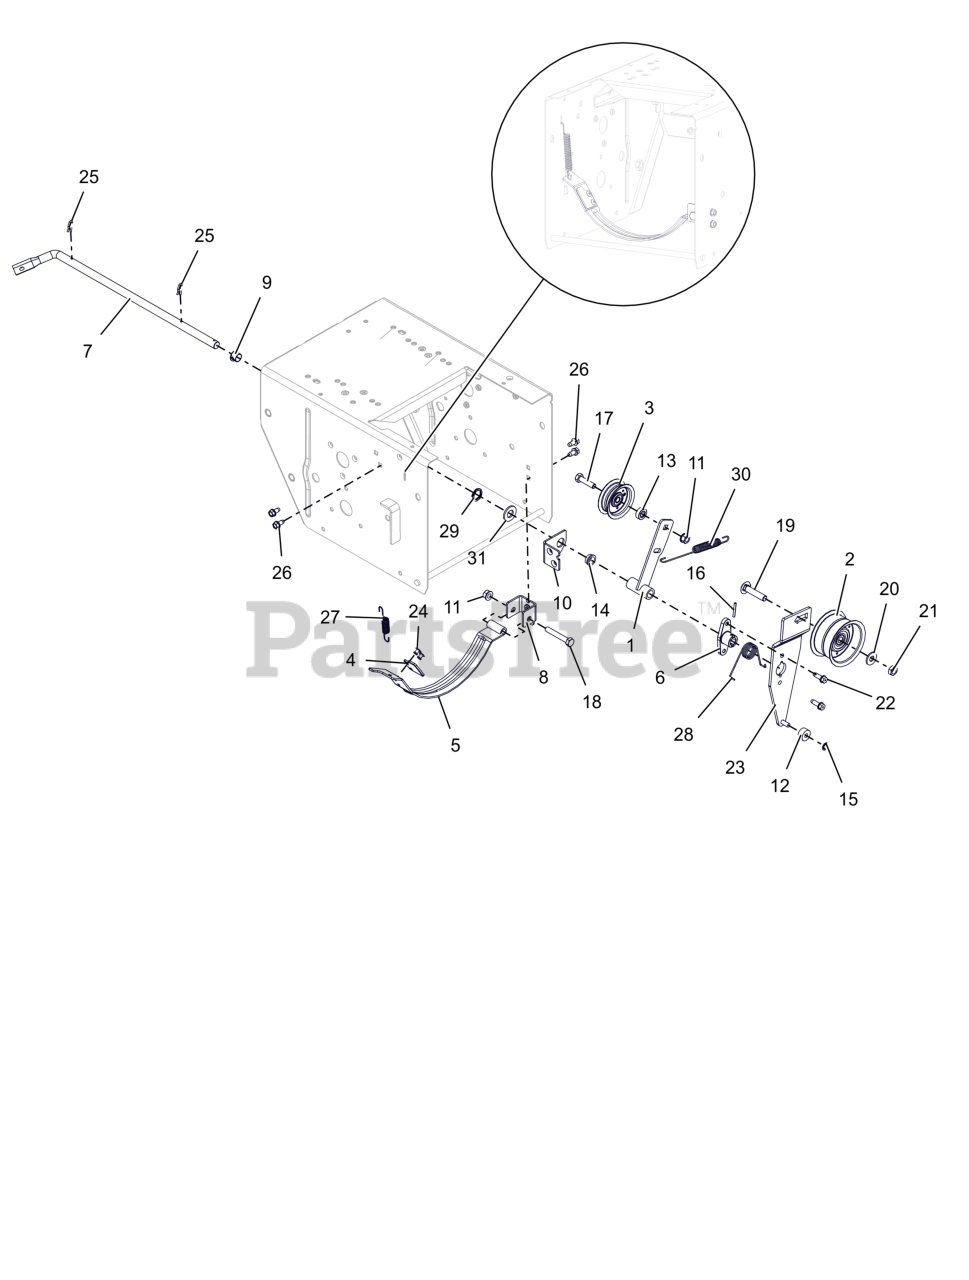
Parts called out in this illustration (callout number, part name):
1	ARM, IDLER-TRACTION
2	IDLER, FLANGE -2.75 OD X .375 ID
3	IDLER, FLAT - 2.00"
4	PAD, BRAKE
5	ARM, BRAKE-ATTACHMENT
6	HUB, BRAKE ARM
7	ARM, ATTACHMENT
8	PIVOT, BRAKE
9	BUSHING, POLYLINER-.50 SPLIT
10	BRACKET, SUPPORT
11	NUT-LK-TOP-FLG .312-18 GF ZCC
12	BSHG,SLV .265 X .625 X .375
13	SPCR, BRG .315X.500X.358X.281
14	BSHG,FLANGE .500X.625X.270X.75
15	RG-RTNG-EXT .250X.010
16	PIN-ROLL .125X1.00
17	BLT, HEX .31-18X1.25 G5 ZCC
18	BLT, HEX .31-18X2.00 G5 ZCC
19	BLT, RHSSN .38-16X1.75 G5 ZCC
20	WSHR,FLT .375X.875X.083 ZCC
21	NUT-LK-CTR-JAM .375-16 GB ZCC
22	SCR,TAP .25-20X.75 HWH TR ZCC
23	ARM, IDLER - ATTACHMENT
24	RVT, POP .1875 ZCC
25	CLIP, SPRING
26	SCR-TAP .25-20X.50 HWH ZCC
27	SPRING-EXT .437 X .438 X 2.64
28	SG-TORS .067X.88
29	WAVE SPRING .600X.875X.25FH
30	SG-TENS .06X.482X5.35
31	WSHR,FLT .531X1.062X.095 ZCC
